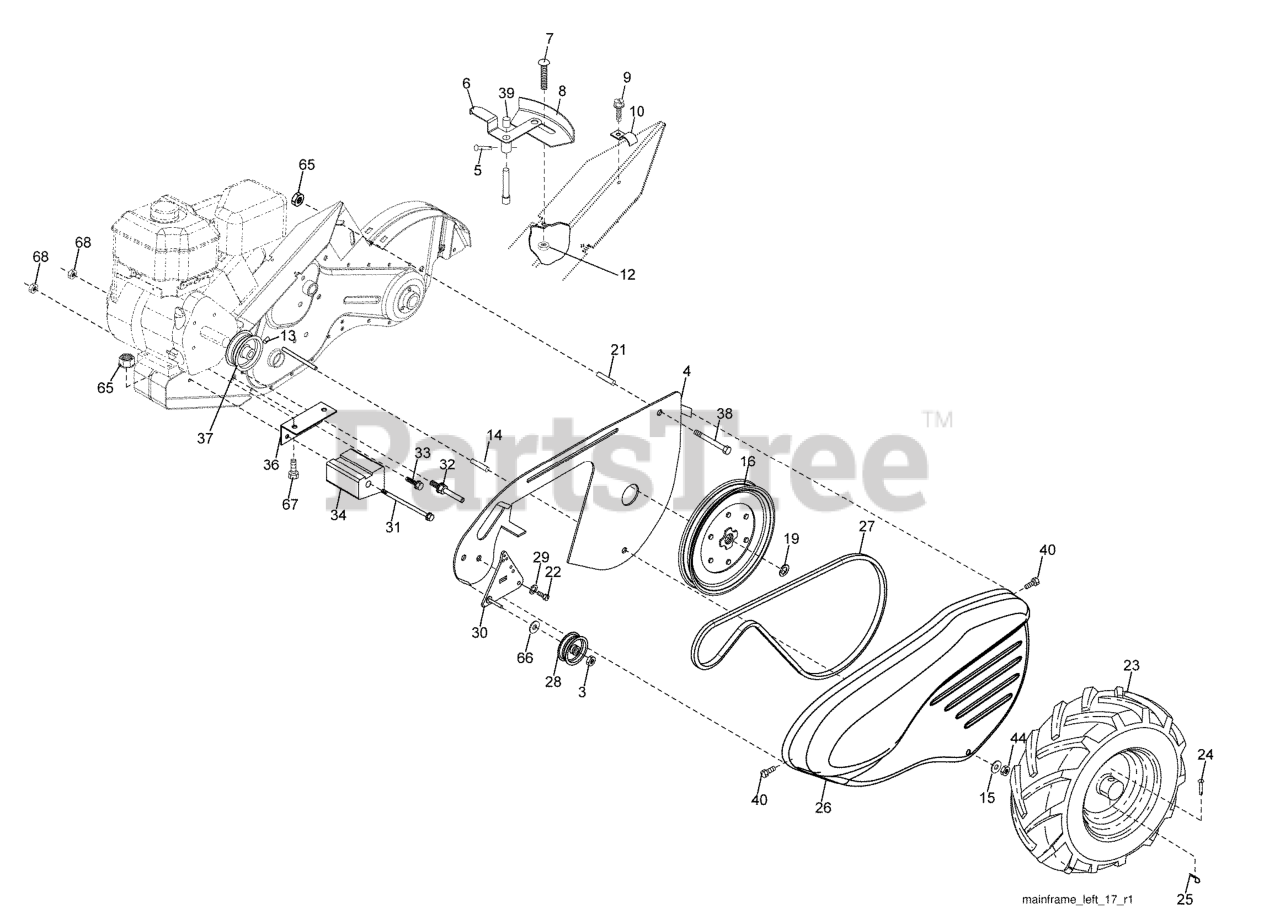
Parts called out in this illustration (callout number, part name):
3	NUT.HEX.3/8-16UNC
4	SHIELD
5	PIN.SPIROL.FLARED
6	LEVER.ASM.SHIFT.RED
8	RP.PANEL.SHIFT
9	TAPPING SCREW
10	CONDUIT.CLIP.PLATED
12	NUT
14	SPACER CRT
15	WASHER
16	SHEAVE, TRANSMISSION
19	RETAINING RING LT
21	SPACER-SPLIT.327 X .42
23	TIRE.13X5-6.CHEVRON.TILLER
24	RIM.ASM.6".SILVER
25	RETAINER M
26	RP BELT GUARD
27	V-BELT
28	PULLEY-IDLER TI
30	BRACKET.ASM.IDLER.BLACK
31	BOLT.FIN.HEX.3/8-16UNC
32	SHIFT ARM CRT
33	BOLT
34	COUNTERWEIGHT.LH.CRT
36	BRACKET LH CRT
37	RP.ENGINE PULLEY
38	BOLT
39	CAP.PLUNGER.BLACK
40	SCREW.HEX.WSH.SLT.#10-24X.50
44	NUT.71038.31-18.HEX.NYLOCK
65	LOCKNUT-FLANGE 5/16-18
66	WASHER
67	BOLT, HEX 5/16-18X1-3/4
